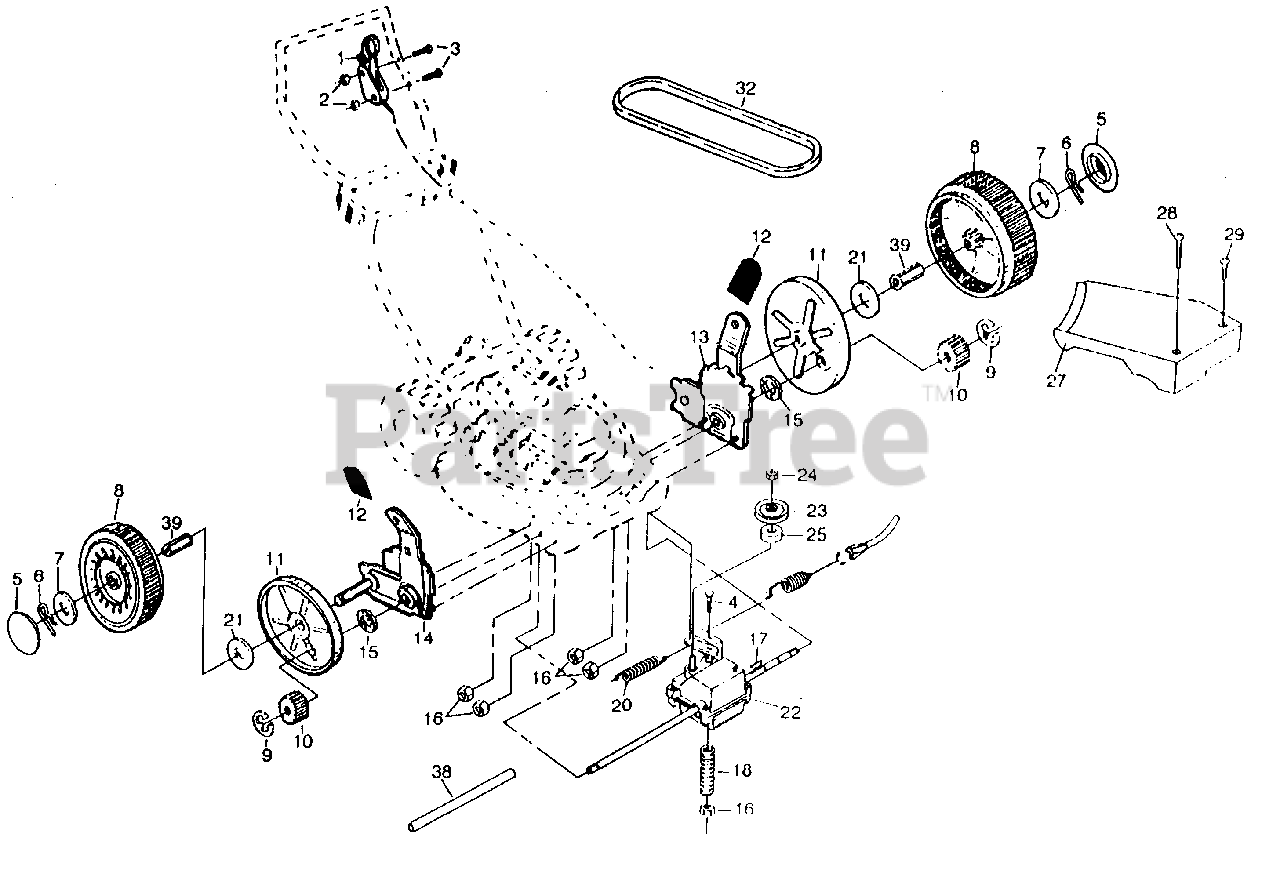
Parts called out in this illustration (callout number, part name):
1	Drive Control
2	Locknut #10-24 (AYP part number)
3	Pan Head Machine Screw #10-24 x 2 (AYP part number)
4	Carriage Bolt 1/4-20 x 2 (AYP part number)
5	Hubcap (AYP part number)
6	Retainer Clip (AYP part number)
7	Washer (AYP part number)
8	Wheel & Tire Assembly (AYP part number)
9	E-ring (AYP part number)
11	Dust Cover
12	Selector Knob
13	Wheel Adjuster Assembly (Left) (AYP part number)
14	Wheel Adjuster Assembly (Right) (AYP part number)
15	Felt Washer (AYP part number)
16	Locknut (AYP part number)
17	Hi-Pro Key (AYP part number)
18	Spring (AYP part number)
21	Washer 1/2 x 1-1/2 x .134 (AYP part number)
22	Gear Case Assembly (AYP part number)
23	Drive Pulley (AYP part number)
24	Locknut (AYP part number)
25	Spacer (AYP part number)
27	Drive Cover
28	Pan Head Tapping Screw #10-24 x 2-3/4 (AYP part number)
29	Pan Head Tapping Screw #10-24 x 1-3/4 (AYP part number)
32	V-Belt
38	Drive Shaft Cover (AYP part number)
39	Wheel Bushing (AYP part number)
